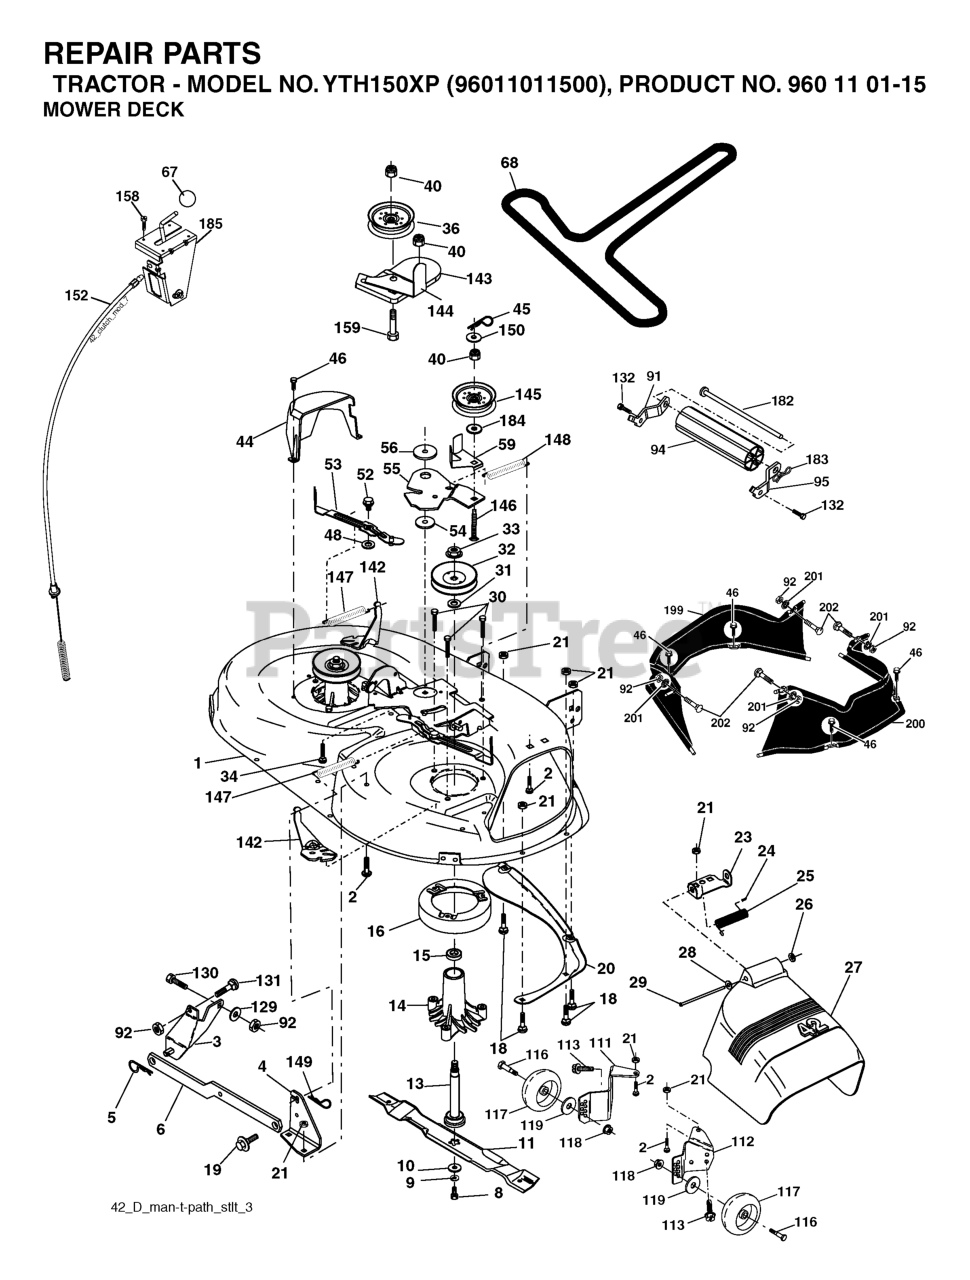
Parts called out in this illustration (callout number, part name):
1	42" DECK KIT
2	RP BOLT 5/16-18 X3/4 ZN/YEL GR
3	BRKT ASM SWAY BAR
4	BRACKET SWAY BAR 42" DECK
5	RETAINER-SPRNG RB
6	BAR SWAY DECK
8	BLADE BOLT
9	LOCKWASHER
10	WASHER.BLADE
11	42" HI-LIFT BLADE
13	SHAFT ASM VENT
14	HOUSING.MANDREL.VENTED (MACHD)
16	STRIPPER.MANDREL.ROUND.BLACK
18	BOLT
19	BOLT SHD 5/16-18
20	BAFFLE.VORTEX
21	LOCKNUT
23	BRKT, DEFL. MOWER
24	CAP-SLEEVE LT
25	SPRING TORSION
26	NUT PUSH M
27	SHIELD ASM.DFLCTR MOWER 42"BLK
28	Washer 11/32 x 5/8 x 16 Ga SD
29	ROD.HINGE
30	SCREW, WASHER HEAD
31	WASHER.SPACER.MANDREL
32	PULLEY/MANDREL
33	NUT, FLG TOPLOCK 9/16"
34	BOLT.3/8-16X1.50
36	FLAT IDLER PULLEY
40	NUT LOCK FLG 3/8-16 UNC
44	GUARD MANDREL LH BLACK
45	RETAINER M
46	SCREW.1/4-20X5/8
52	BOLT.SHOULDER.5/16-18
53	ARM BRAKE ASSY
55	ARM IDLER 42" MOWER LT/YT
56	SPACER.RETAINER.MOWER
59	GUARD, BELT
67	KNOB T (3/8 HOLE)
91	BRACKET ASM NOSEROLLER LH
92	NUT
94	NOSE ROLLER
95	BRACKET ASM NOSEROLLER RH
111	BRACKET, WHEEL
112	BRACKET, WHEEL
113	BOLT.5/16HEX.WHS.HD
116	BOLT M
117	WHEEL.GAGE.HALF.SPOKED
118	LOCKNUT
119	WASHER.5/16.FLAT.STE.STD.
129	WASHER
131	BOLT D
132	SCREW, 3/8-16X3/4
142	ARM SPRING BRAKE MOWER
143	BRACKET, ARM IDLER
144	DNO KEEPER.BELT.42".CLUTCH.CBL
145	PULLEY
146	BOLT, CARRIAGE IDLER BLACK
148	IDLER RETURN SPRING
149	SPRING.RETAINER.YELLOW.ZINC
152	CABLE.CLUTCH.42"
158	SCREW
182	ROD ROLLER NOSE STANDARD
183	PIN.COTTER.7/16.BOW TI.
184	WASHER
185	HEAD ASM. CABLE CLUTCH
198	SCREW, 5/16-18 X 1/2
201	PUSH.NUT.ROUND.3/8.DIAM
202	BOLT D
204	NUT, CROWNLOCK
